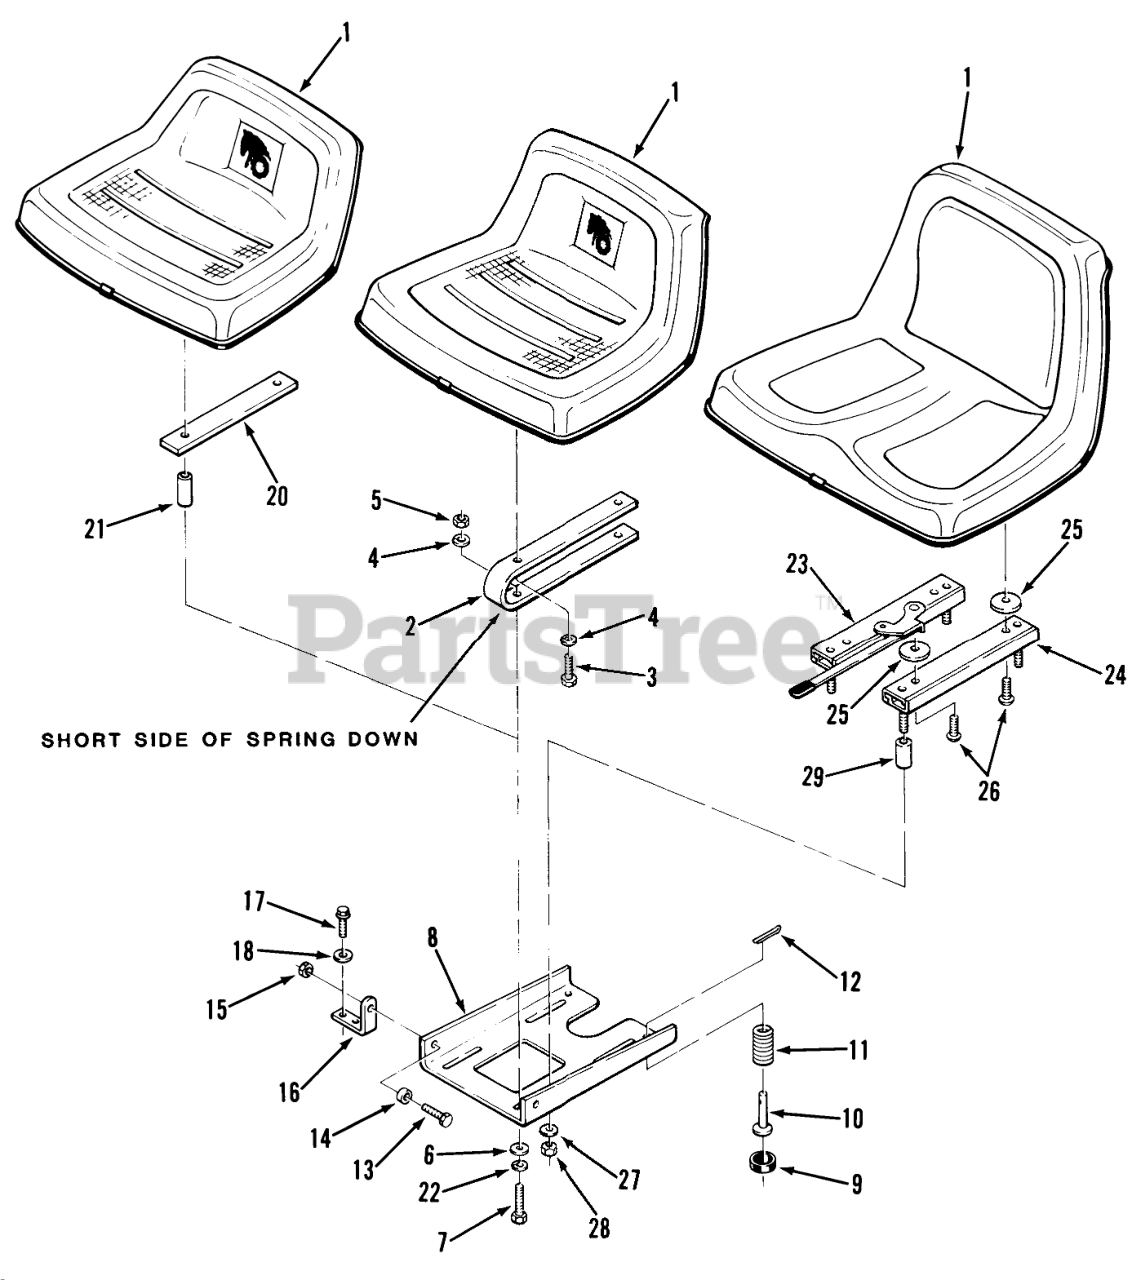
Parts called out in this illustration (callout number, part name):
6	WASHER 5/16 SAE
11	SPRING
14	BUSHING
18	WASHER 5/16 SAE
21	SPACER SEAT *B
25	SPACER-NYLON
